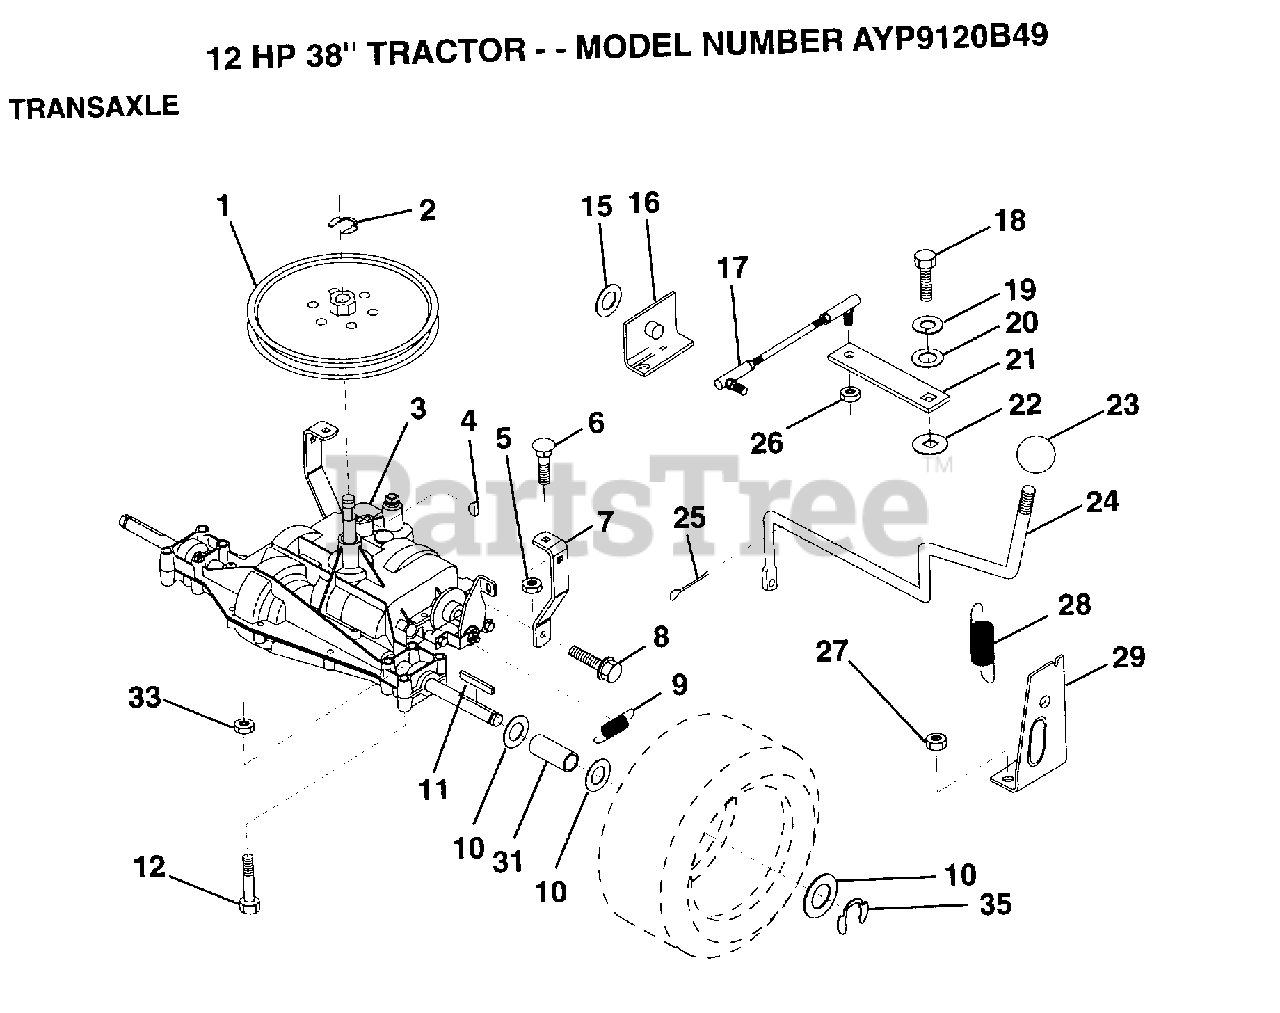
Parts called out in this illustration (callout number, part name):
1	PULLEY
5	NUT
6	BOLT
7	"STRAP,TORQUE"
8	SCREW
10	WASHER
11	SQUARE KEY
12	BOLT
16	"SUPT,HDLE SHT LH"
17	"LINK,SHIFT"
19	LOCKWASHER
20	WASHER LT
21	ARM SHIFT
22	WASH-SHFT PLT LT
23	KNOB T (1/2-HOLE)
24	"ROD,SHIFT"
25	PIN COTTER 1/8
26	NUT.LOCK.5/16-24
28	"SPRING,EXT"
29	"SUPT,HDLE RH"
31	SPACER LT
33	NUT
35	E-RING LT
